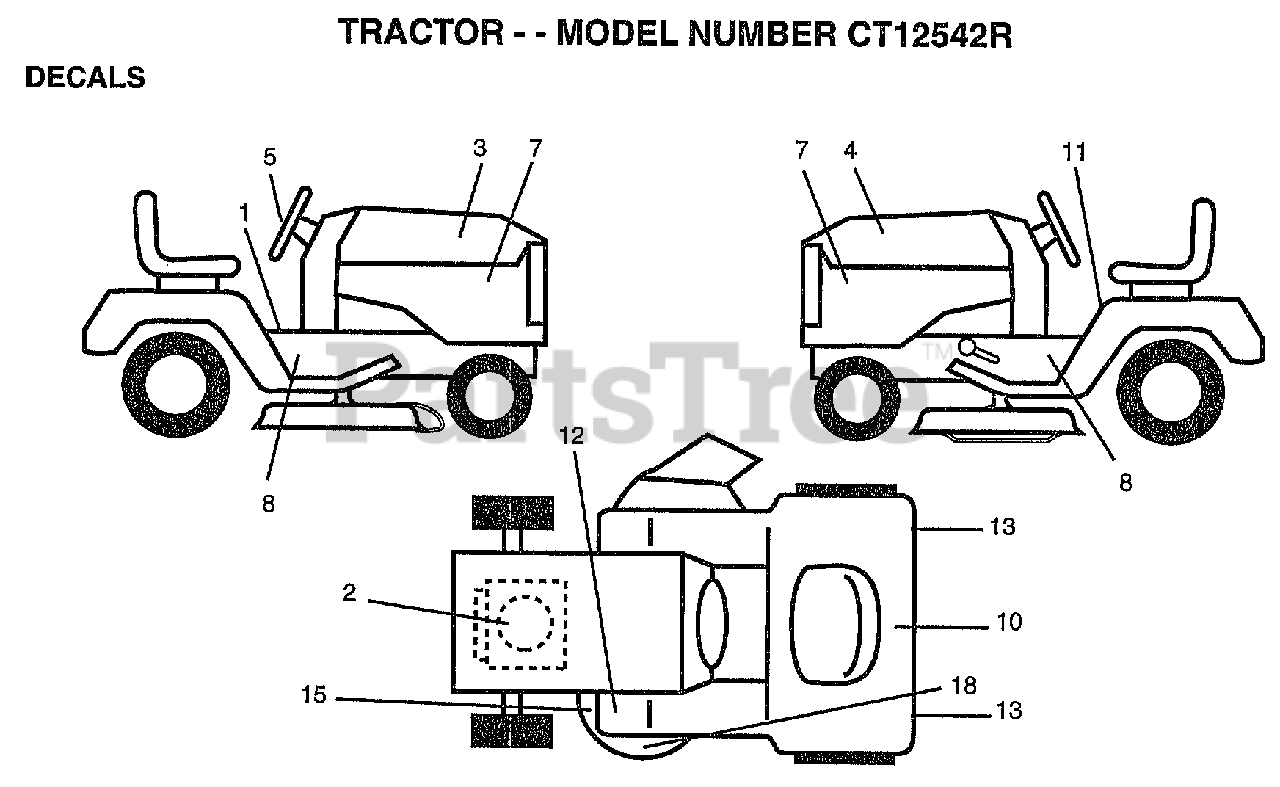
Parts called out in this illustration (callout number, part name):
1	"DECAL DASH,OPER."
2	DECAL, HP ENGINE
3	DECAL HOOD RH
4	"DECAL HOOD,LH"
5	DECAL INST STG WH
7	"DECAL PANEL,SIDE"
8	"DECAL CHASSIS 42"""
10	DECAL.BATRY.3-3908
11	"DECAL DANGER,FEND"
13	REFLECTOR-TAIL YT
15	"DECAL-SCHEM,BELT"
18	"DECAL,ENVIRO DECK"
